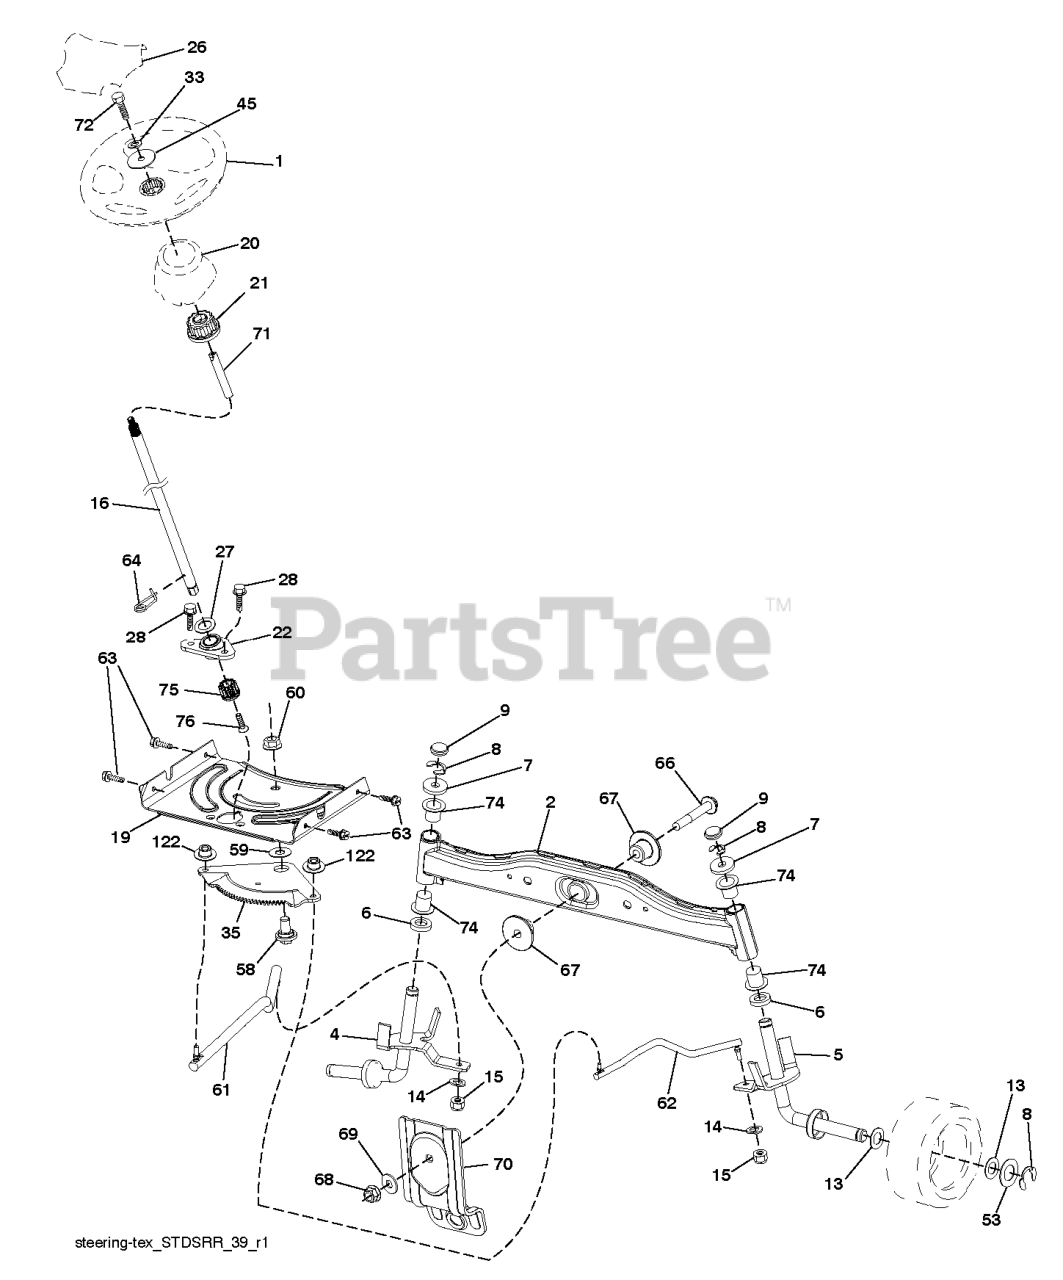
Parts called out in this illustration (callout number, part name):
1	WHEEL.STEERING.HUSQ.PREM.HRDRM
2	AXLE HALF ASM-WELDED
4	SPINDLE.WELDED.LH.15"TEX
5	SPINDLE.WELDED.RH.15"T
6	THRUST WASHER
9	CAP.SPINDLE.BLACK
15	NUT CROWNLOCK 3/8-24
16	3 HIGH.SHAFT-ZINC.PLATED
19	PLATE.STEER.DDL.NLT/NG
20	STEERING.BOOT.HUSQ.LT
21	ADAPTER, WHEEL STNG..
22	BEARING.SHAFT.STEER.LOWER.625
26	INSERT.CAP.WHL.STRG.HUSQ.PREM
28	SCREW, 3/8-16X3/4
33	WASHER SPRING LOCK WASHER WITH
35	GEAR.SECTOR.PLATE.DDL.
53	WASHER.HARDENED
58	BOLT.SHOULDER.SECTOR.P
59	WASHER.THURST.SECTOR.S
60	NUT FLANGE LOCK 5/8-11
63	SCREW
64	RETAINER.CLIP.SPRING.S
66	BOLT HEX FGHD 7/16-14 X 3 SERR
67	BUSHING.PM.FRONT AXLE
68	NUT.LOCK.FLANGE.7/16
69	WASHER.1.5X.505X.118
70	BRACKET.FRT.DECK.SUSP.RR.MT431
71	SHAFT.EXTEN.STRG.SPLINE
74	BEARING.STEERING.COLUMN
75	PINION.ZINC PLATED
76	SCREW HEAD SOCKET LRVB
122	CAP.GEAR.SECTOR.TEX
